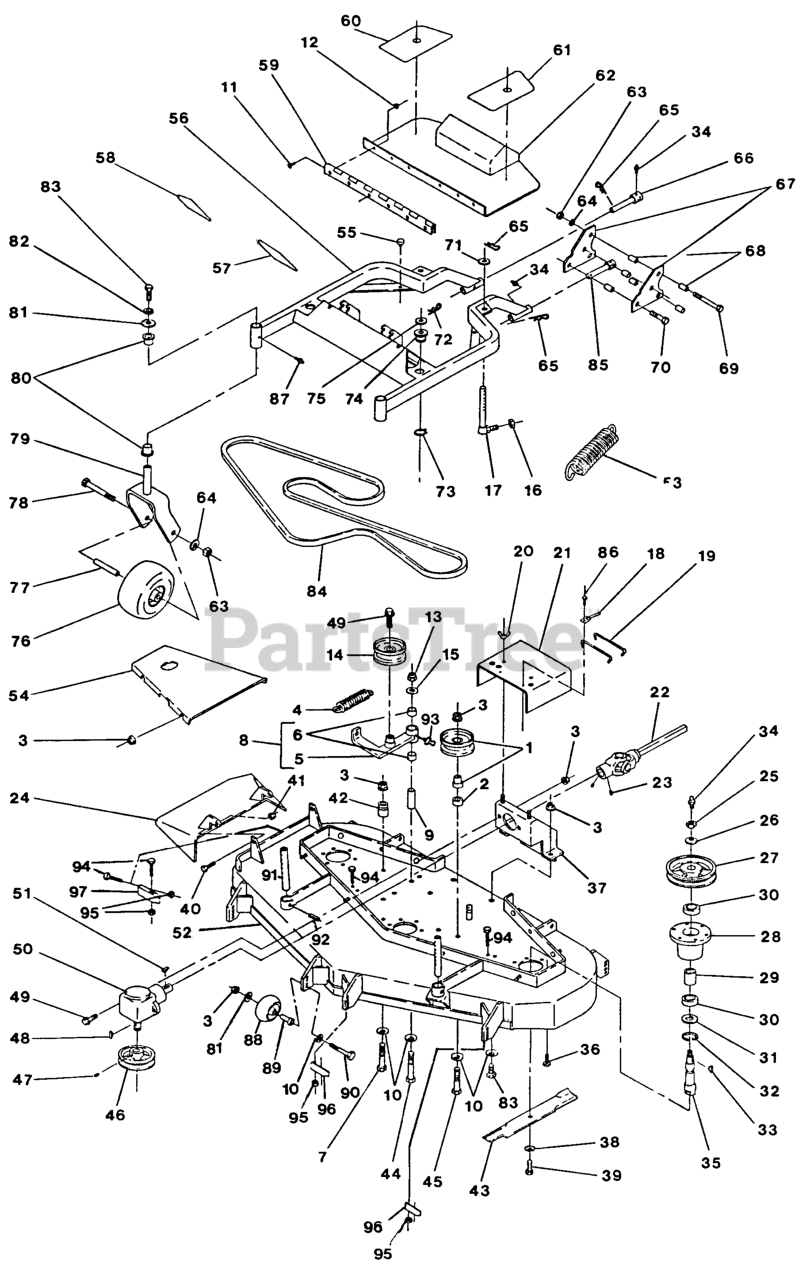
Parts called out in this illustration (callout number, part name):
1	KIT,48 RH IDLER/BUS
4	SPRING,EXTENSION
6	SLEEVE-BEARING
9	BUSHING
14	IDLER,PULLEY
18	CLIP-DECK, HOLD UP ROD
19	PAD,ANTI SKID UPPER RH
20	WINGNUT-NYLOCK
22	PTO SHAFT,SHAFT HALF PNT
24	WLD,CHUTE DISCHARGE
26	WASHER-SPRING
27	SHEAVE,BLADE DRIVE
29	SPACER,BEARING
31	SEAL,MECHANICAL DUST
32	RING,SNAP WLDS N5000-244
35	SPINDLE-OUTER BLADE
36	SCRW,TPTTE HH
37	WLD,GEARBOX SUPPORT
38	WASHER-SPRING
42	ANCHOR-SPRING PLTD
47	SCREW-SET
50	GEARBOX, PEERLESS
57	PAD,ANTI SKID UPPER LH
58	PAD,ANTI SKID UPPER RH
59	HINGE,FLOORPAN
60	PAD,ANTI SKID LOWER RH
65	PIN,HAIR COTTER
71	SPACER,REAR DK SUPP PLTD
74	BUSHING-DECK
75	SPACER-CASTER
80	BEARING-FLANGED
86	Pop Rivet, Steel 3/16 X .250
88	ROLLER-SCALP, ANTI
89	BUSHING-ROLLER
91	ROD,DECK SUPPORT
97	WLD,BAFFLE DISCHARGE
